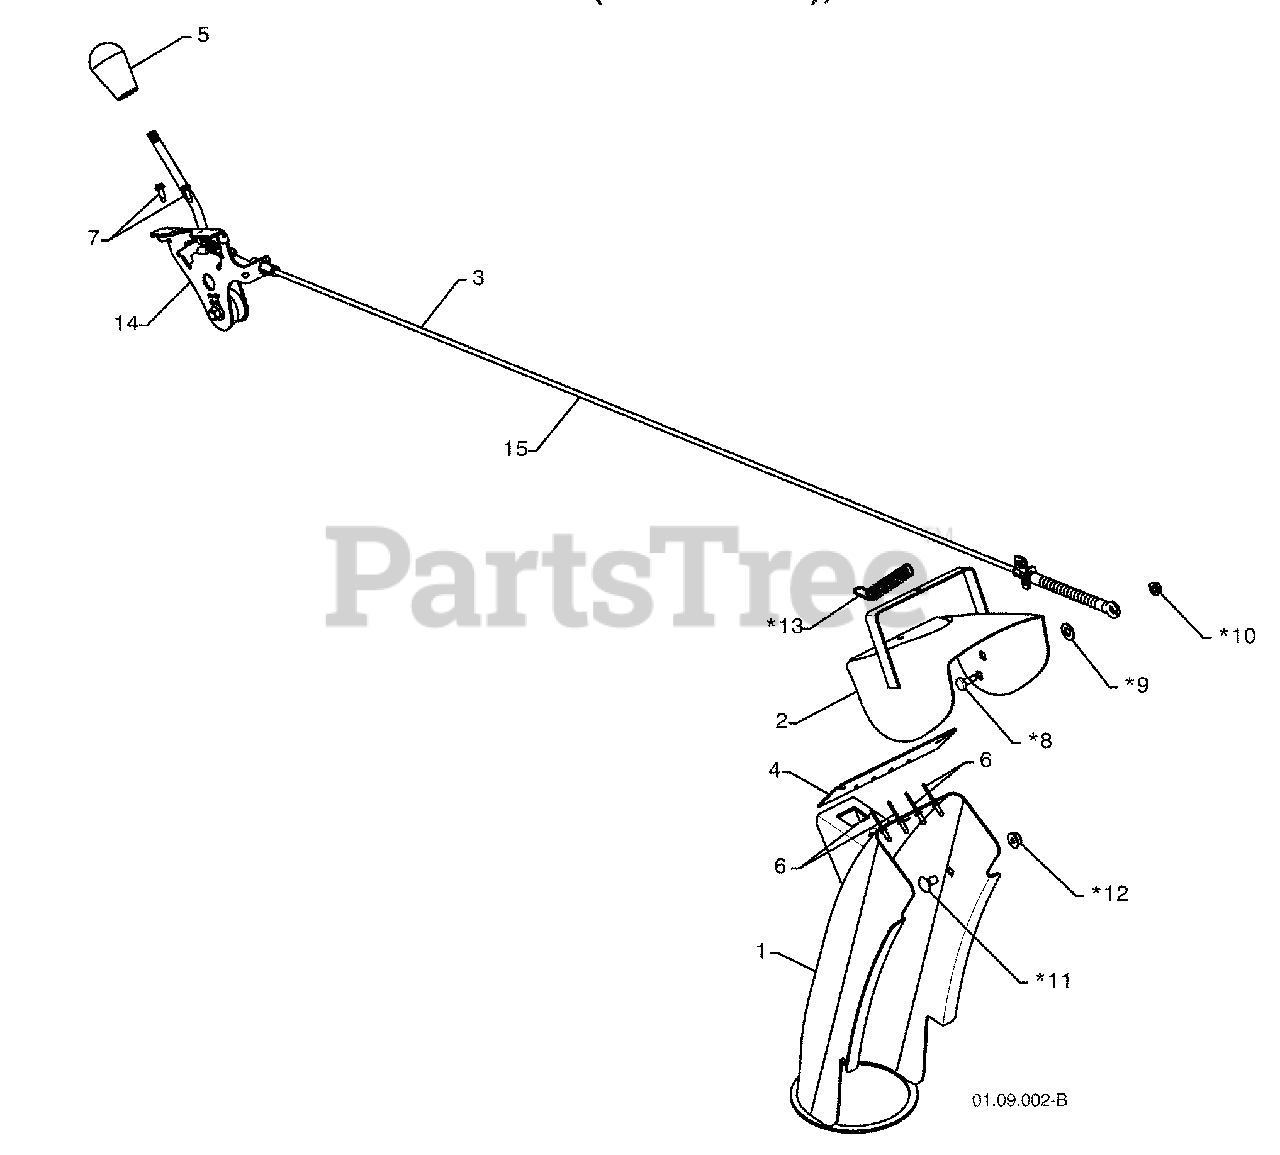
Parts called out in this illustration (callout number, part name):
1	CHUTE WELDMENT
2	DEFLECTOR WELDMENT
3	DEFLECTOR CONTROL ASSEMBLY
4	DEFLECTOR SEAL
5	KNOB BLACK
7	SCREW 10-24 X .625
8	SHOULDER SCREW
9	PLASTIC WASHER
10	NUT 1/4-20
11	CARRIAGE BOLT 5/16-18 X .50
12	NUT 5/16-18
13	DEFLECTOR SPRING
14	SERVICE PART) DEFLECTOR CONTROL HEAD
15	SERVICE PART) DEFLECTOR CONTROL CABLE
